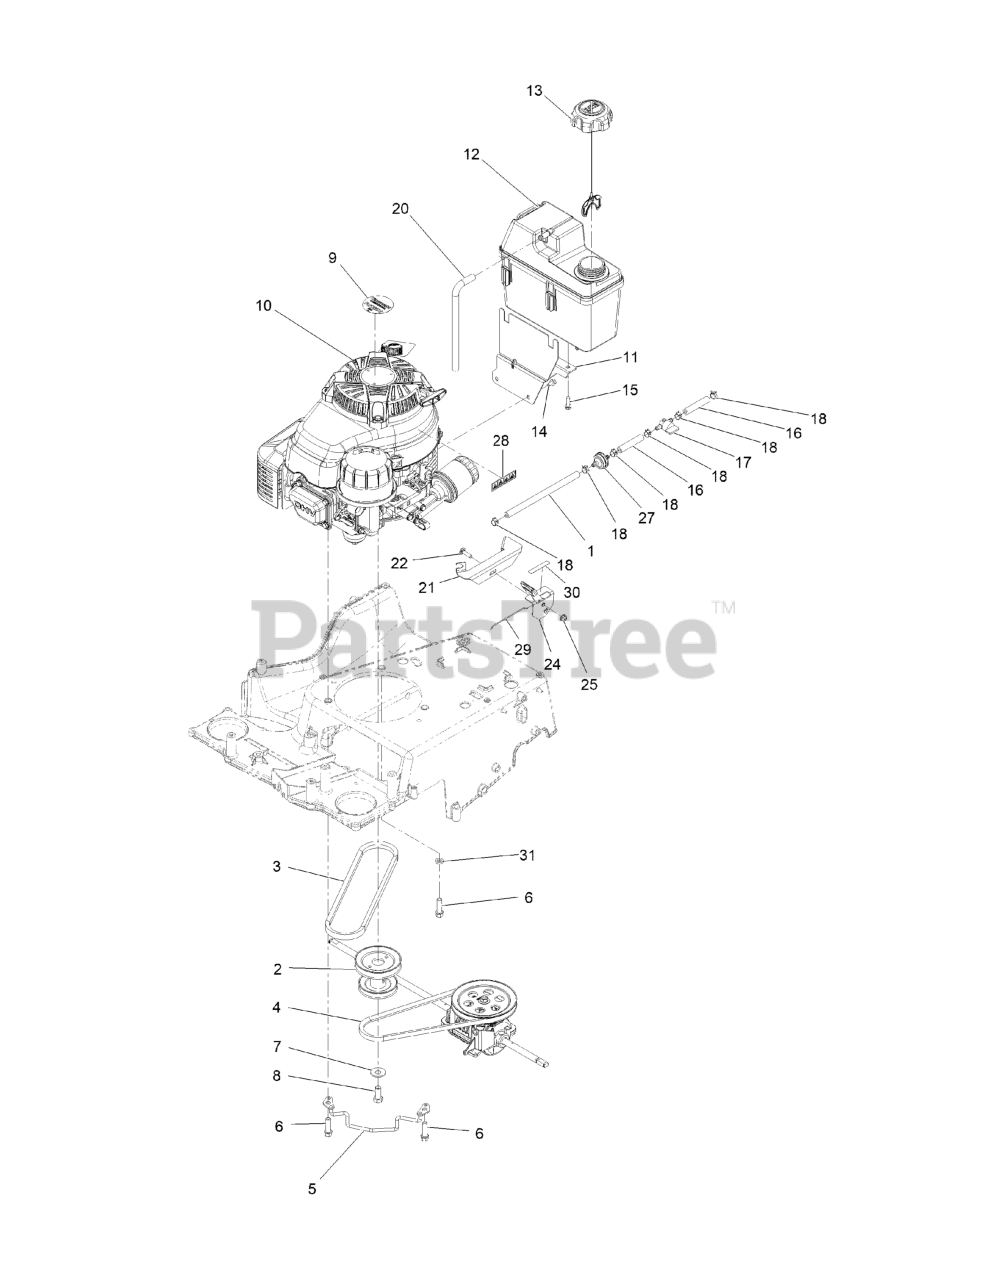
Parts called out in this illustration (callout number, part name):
1	HOSE-FUEL
2	PULLEY-ENGINE
4	BELT
5	GUIDE-BELT, WA
6	SCREW-TAPTITE
7	WASHER-BELLEVILLE
8	SCREW-HH
11	MOUNT-TANK
12	TANK-FUEL
13	CAP-FUEL
14	SCREW-HWH
15	SCREW-HWH
16	HOSE-FUEL
17	VALVE-FUEL
18	CLAMP-HOSE
20	HOSE-VENT, CANISTER
21	BRACKET-MOUNT, THROTTLE
22	SCREW-CARR
24	CONTROL-THROTTLE
27	Filter-Fuel
28	DECAL-WARNING, ENGINE
29	WIRE-CONTROL
30	DECAL-THROTTLE, CHOKE
31	SPACER
